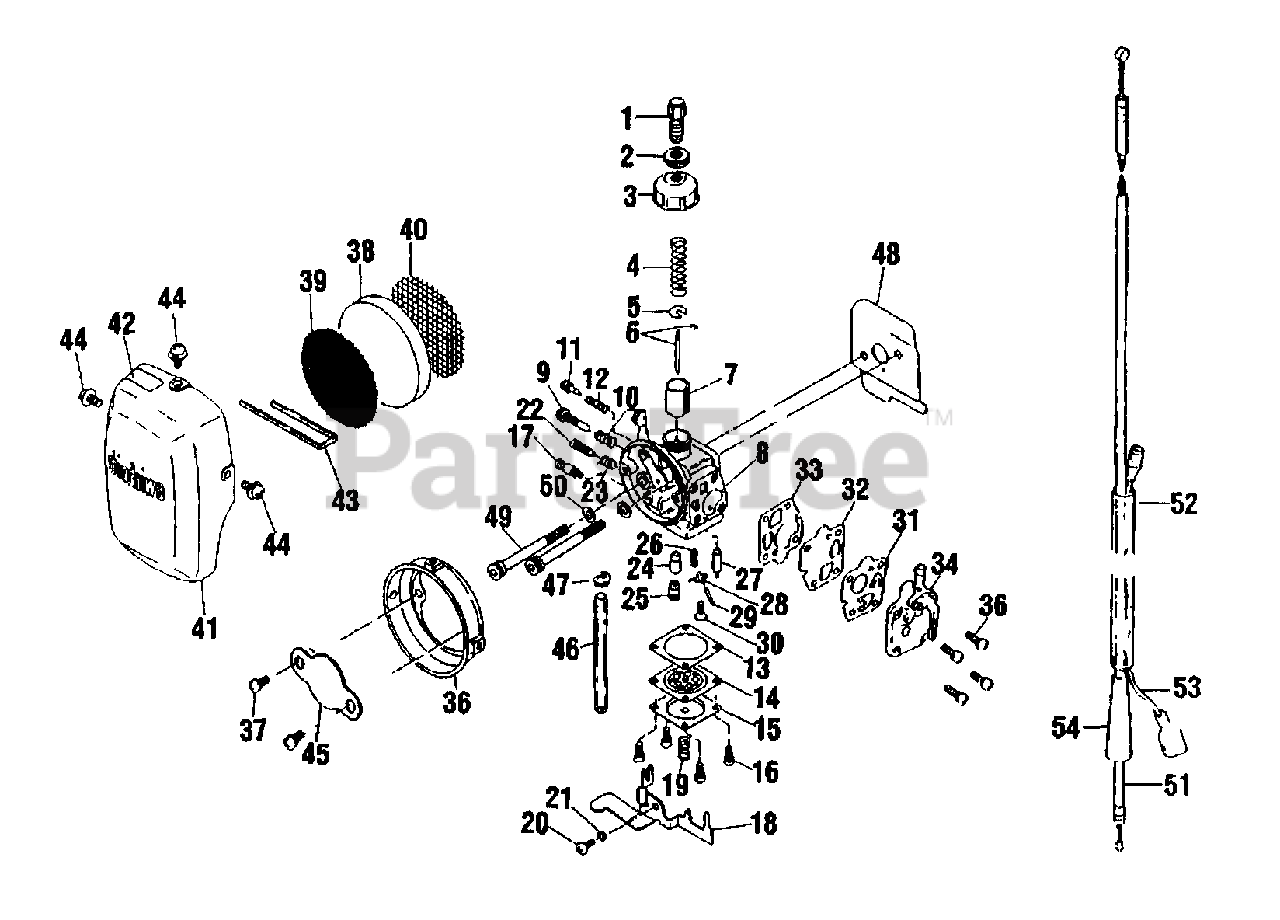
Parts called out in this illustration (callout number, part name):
1	ADJUSTER, CABLE
2	LOCKNUT
3	CAP, CARBURETOR
4	SPRING, THROTTLE
5	WASHER
6	NEEDLE
7	VALVE, THROTTLE
8	BODY, CARBURETOR
9	SCREW, IDLE ADJUST
10	SPRING
11	SCREW, SLOW AIR
12	SPRING
13	GASKET
14	DIAPHRAGM
15	COVER, METERING DIAPHRAGM
16	SCREW M3×8
17	VALVE, OVERFLOW
18	LEVER, TICKLER
19	SPRING
20	SCREW
21	COLLAR
22	SCREW, ADJUST
23	SPRING
24	JET
25	HOLDER, MAIN JET
26	SPRING
27	VALVE, INLET NEEDLE
28	LEVER
29	PIN, METERING LEVER
30	SCREW, METERING LEVER PIN
31	VALVE, PUMP
32	DIAPHRAGM, METERING
32	DIAPHRAGM
33	GASKET, DIAPHRAGM
33	GASKET
34	PUMP BODY
35	SCREW
36	CASE, AIR FILTER
37	SCREW
38	FILTER, AIR
39	SCREEN - FRONT
40	SCREEN, REAR
41	COVER, AIR FILTER
42	PLATE - GROUND
43	CLIP, FILTER RETAINING
44	SCREW 4
45	PLATE
47	CLIP Ø6
48	SHIELD, INTAKE
49	BOLT M5×48
50	WASHER, SPRING 5
51	CABLE, THROTTLE
52	TUBE
53	LEAD - GROUND
54	CAP, CABLE
